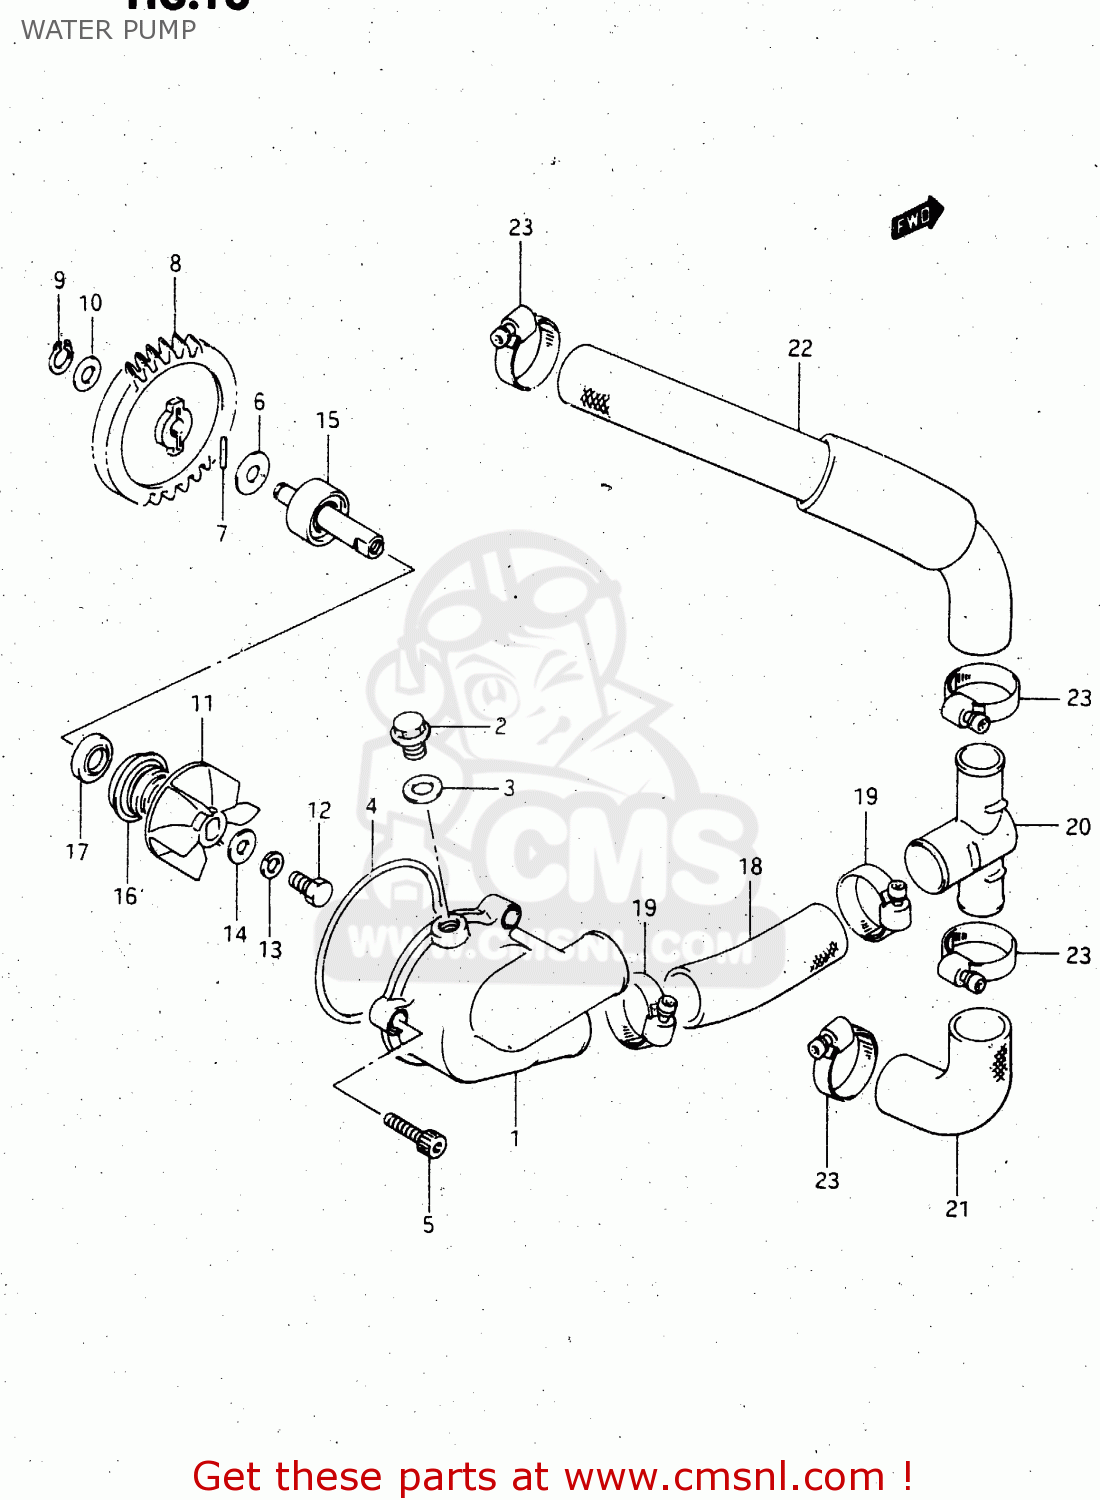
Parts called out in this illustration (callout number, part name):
1	CASE,WATER PUMP
2	BOLT,DRAIN
3	GASKET 8.2X14X1 (NAS)
4	O RING,WATER PUMP CASE
5	BOLT ,6X20
6	WASHER
7	PIN(2.5X19.8)
8	GEAR,WATER PUMP DRIVE(NT:31)
9	CIRCLIP
10	WASHER
11	IMPELLER,WATER PUMP
12	BOLT(6X13)
13	WASHER
14	GASKET(6X15X2.2) (NAS)
15	SHAFT,WATER PUMP
16	SEAL,MECHANICAL
17	SEAL,OIL(10X20X5)
18	HOSE,WTR PUMP OUTLET
19	CLAMP
20	UNION,WTR HOSE THREE WAY
21	HOSE,CYLINDER INLET NO.1
22	HOSE,CYLINDER INLET NO.2
23	CLAMP
